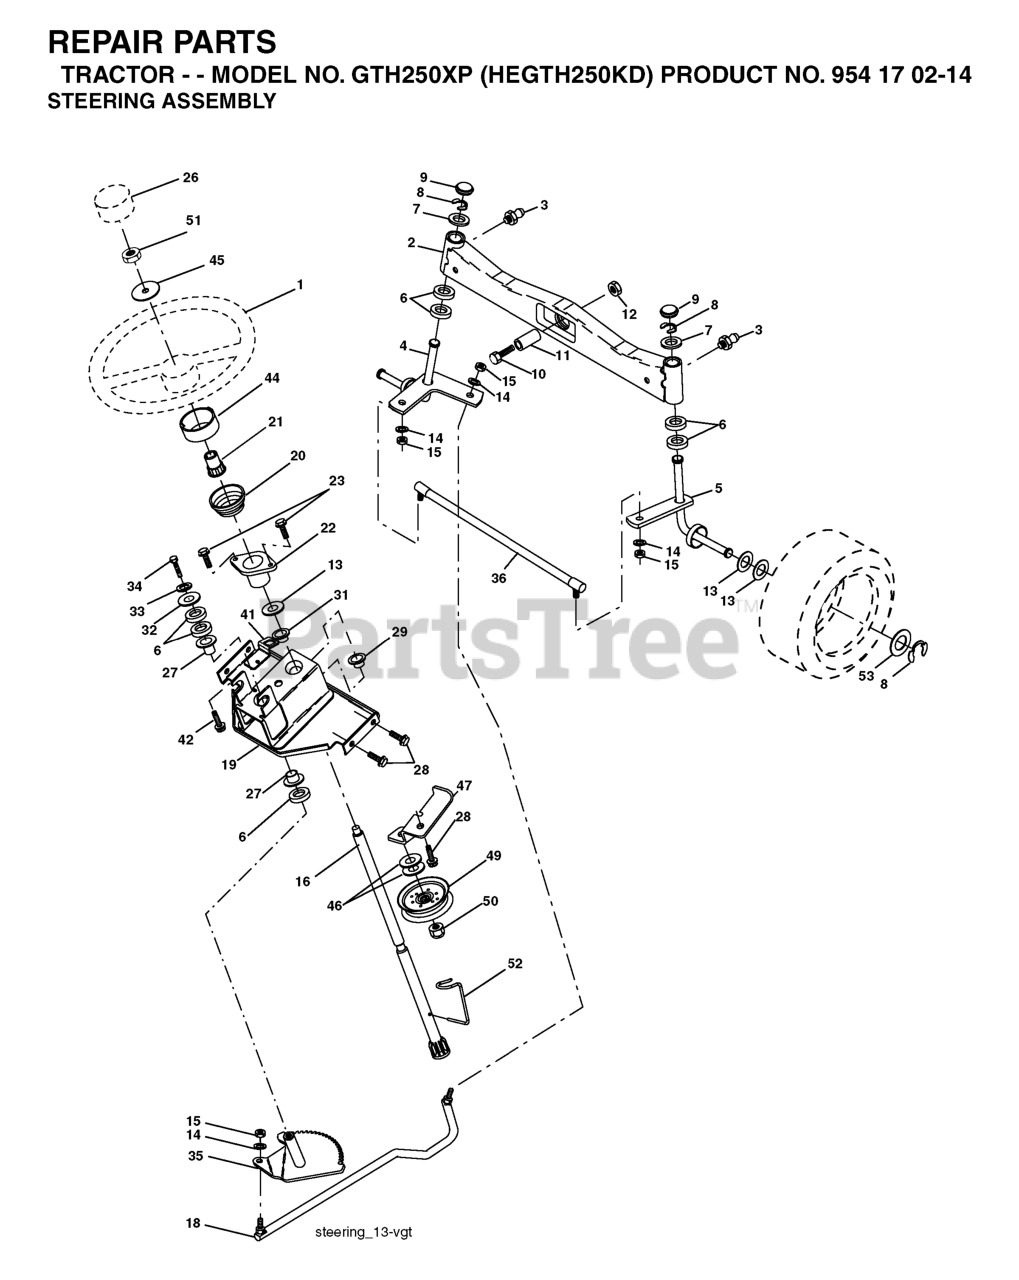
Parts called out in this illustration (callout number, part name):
1	STEERING WHEEL
2	AXLE.FRONT.CAST.MACHINE.W/ZERK
3	FITTING.GREASE.TAPERED
4	SPINDLE ASSY LH
5	SPINDLE ASM RH
6	THRUST WASHER
9	CAP.SPINDLE.BLACK
10	Bolt, Hex 5/8 -11 x 2 - 3/4 Gr. 5
11	TUBE, PIVOT AXLE
12	NUT-LOC,FLANGE LT
14	WASHER, LOCK 3/8
15	NUT CROWNLOCK 3/8-24
16	SHAFT ASM, STEERING
18	DRAGLINK, BALL JOINT (3SPG1401
19	SUPPORT ASM., STEERING VGT
20	BOOT, STEERING
21	STEERING WHEEL ADAPTOR
22	BUSHING, STRG. BLK
23	SCREW.TT.#10-32X.5.3/8.FLANGE
26	CAP.WHEEL.STEERING.GREY
27	BRNG T
28	SCREW, 3/8-16X3/4
29	BEARING-FLANGE GT
31	BUSHING.NYLINER.
33	WASHER.LOCK.HVY.HLCL.SPR.5/16
34	BOLT.FIN.HEX.5/16-18X3/4
35	GEAR.ASM.SECTOR.
36	ROD.TIE.NON-ADJUSTABLE
41	BRACKET INTERLOCK
42	Screw 5/16-18 x 1/2 Hex, Self Tapping 5/16-18 x 1/2
44	EXTENSION STEERING PREMIUM
45	Washer 9/16 ID x 1 1/2 OD 11 Ga. Zin
47	BRKT.ASM.IDLER.STATIONERY
49	PULLEY.IDLER.FLAT.46.PR.DR.
50	NUT LOCK FLG 3/8-16 UNC
51	NUT.HEX.1/2-20
52	CLIP.STEERING
53	WASHER.HARDENED
